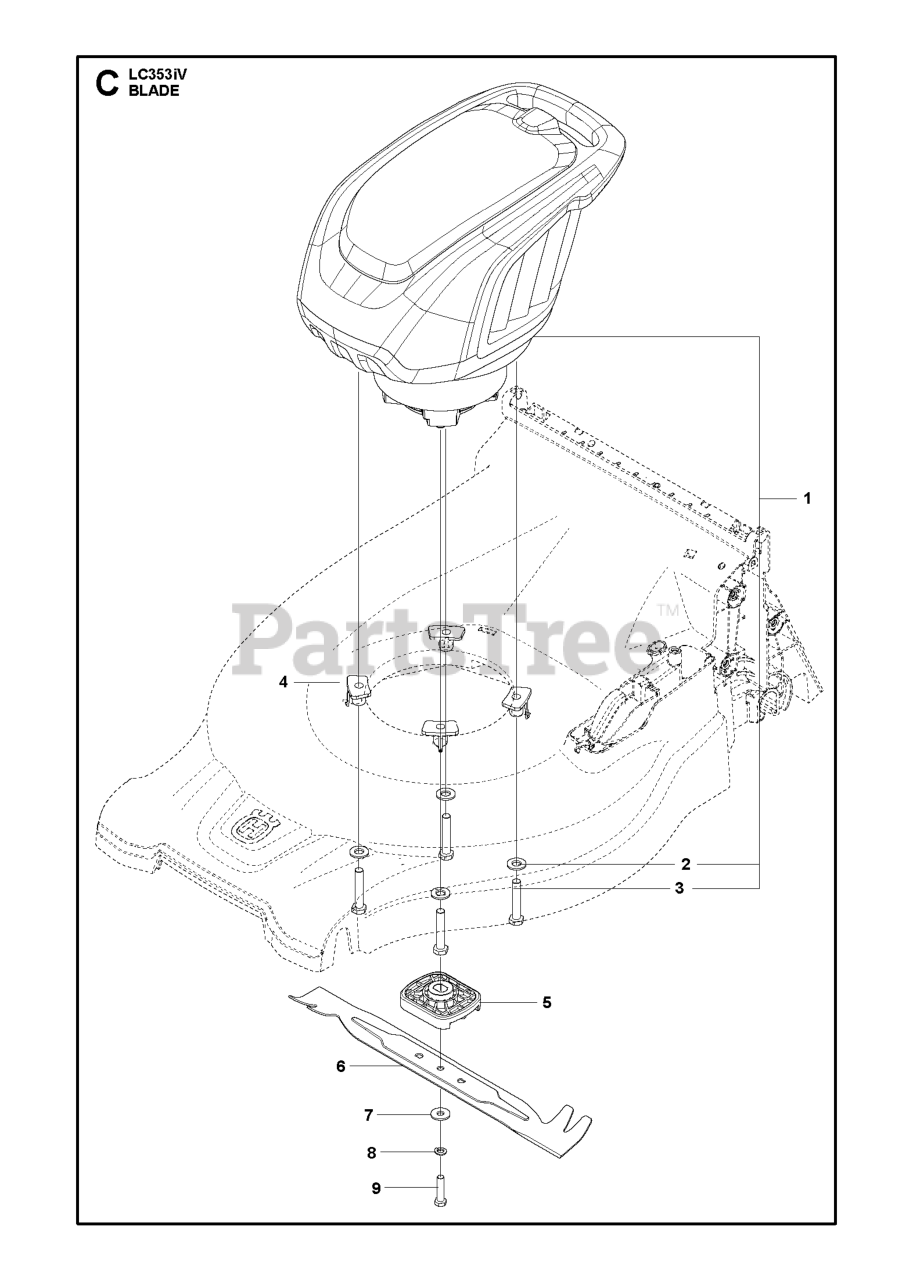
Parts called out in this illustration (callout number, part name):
3	SCREW
7	SPACER
8	SPRING WASHER
9	SCREW
